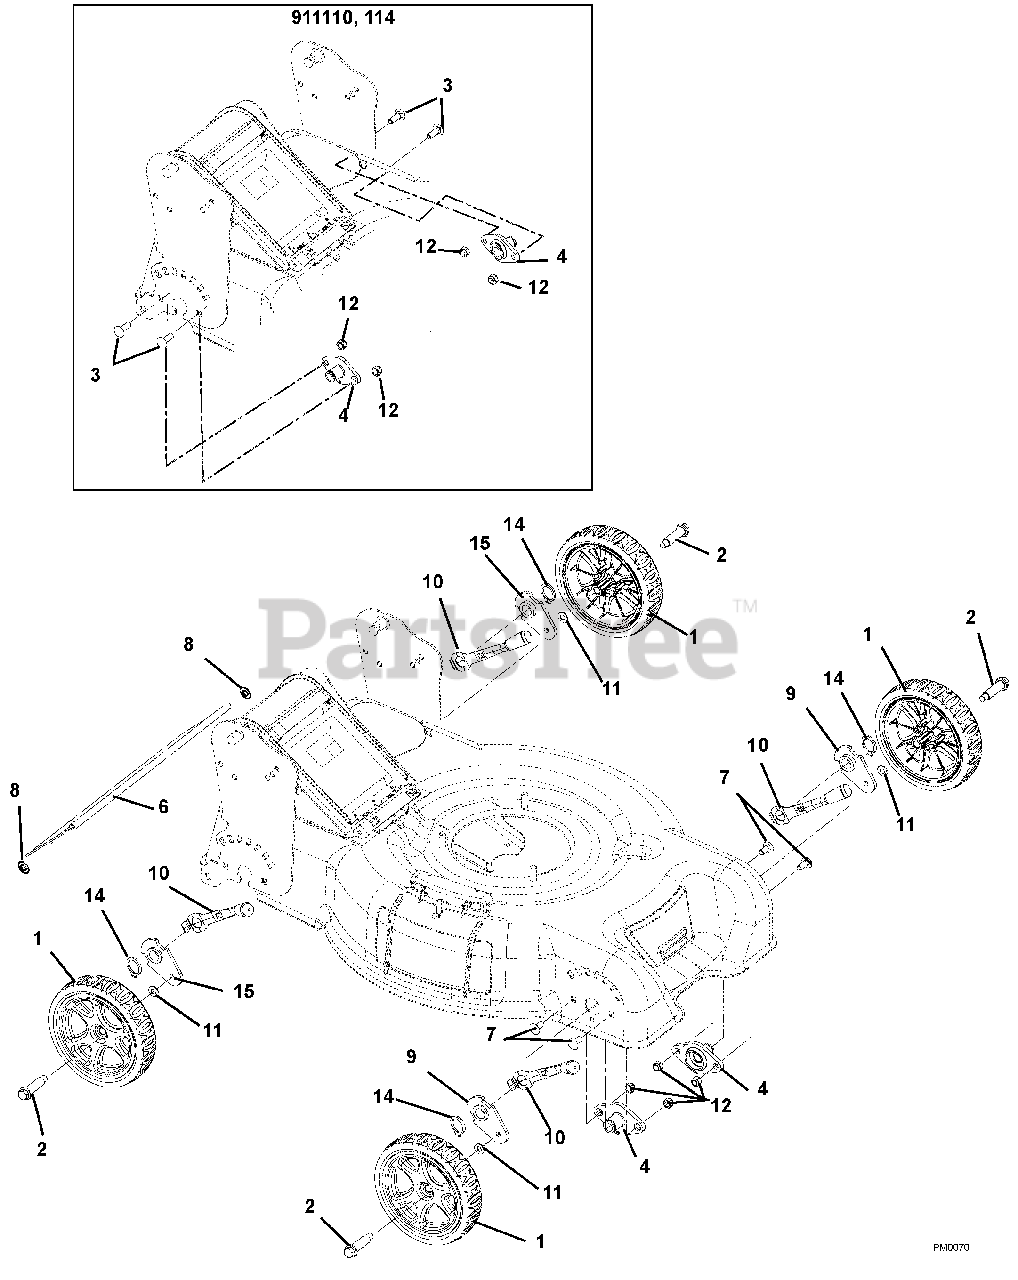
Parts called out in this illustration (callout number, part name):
1	WHEEL-8.5" WBLM ASSY
2	BOLT, WHEEL SHOULDER
3	@BLT-RDHDSQNK .31-18X1.00 G5YZ
4	WHEEL MOUNT HUB
5	WHEEL MOUNT HUB
6	GUARD, WBLM
7	@BLT-RHDSSQNK .31-18X.75 G5YZ
8	RETAINER, .38 PUSH-ON
9	PLATE, FRONT WHEEL MOUNT
10	HANDLE, HOC
11	@WSHR-FL-STL.406X.812X.065 YWZ
12	@NUT-LK-TOP-FLG .31-18 YWZC
13	@NUT-LK-TOP-FLG .31-18 YWZC
14	RG-RTNG-EXT .689X.078
15	PLATE, REAR WHEEL MOUNT
